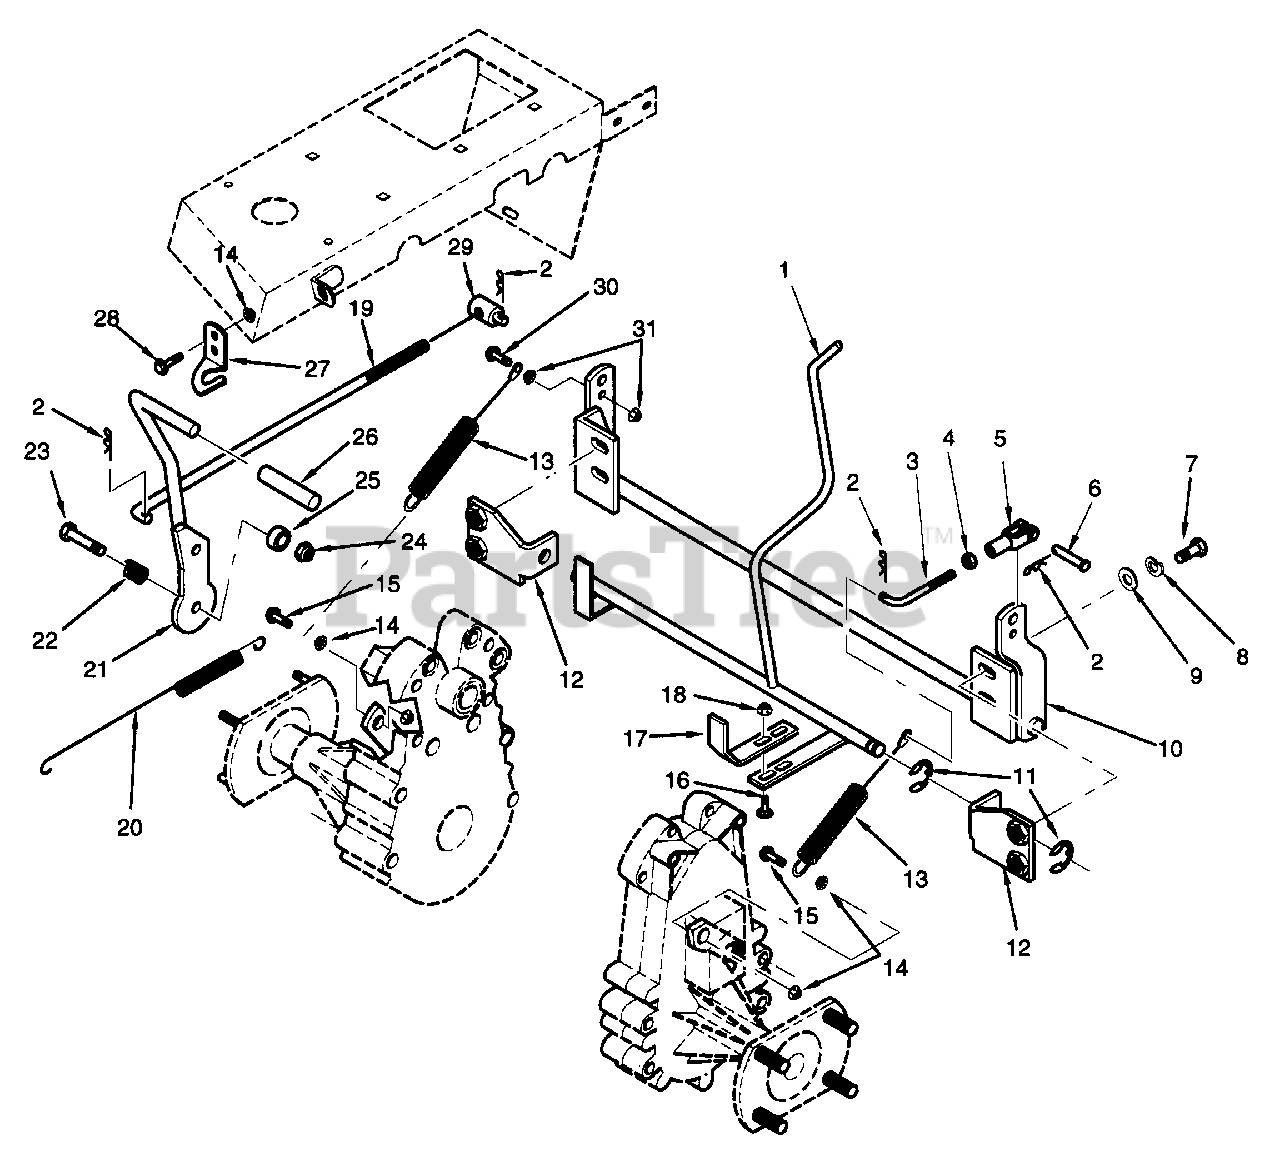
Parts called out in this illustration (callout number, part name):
1	LEVER, DUMP VALVE
2	HAIRPIN
3	ROD, BRAKE - L.H.
4	HEX NUT, 1/4-28
5	CLEVIS
6	PIN, CLEVIS, 1/4 X 3/4
7	BOLT, HEX HEAD, 3/8-16 X 1-1/2
8	LOCKWASHER, 3/8
9	FLATWASHER, 3/8(.391 X .938 X .105)
10	ACTUATOR, BRAKE
11	RING, RETAINER
12	MOUNTING BRACKET, DUMP VALVE
13	CABLE ASSEMBLY, PARKING BRAKE
14	SERR. FL. HEX NUT, 5/16-18
15	SERR. FL. HEX HEAD CPSCR, 5/16-18 X 1.00
16	CARRIAGE BOLT, 1/4-20 X 3/4
17	BRACKET, DUMP VALVE LEVER
18	SERR. FL. HEX NUT, 1/4-20
19	ROD, BRAKE - R.H.
20	SPRING
21	LEVER, PARKING BRAKE
22	SPRING, CONTROL DETENT
23	BOLT, HEX HEAD, 3/8-16 X 2-1/4
24	HEX LOCKNUT, ELASTIC STOP, 3/8-16
25	SPACER
26	GRIP, PARKING BRAKE LEVER
27	LATCH, BRAKE LEVER
28	SERR. FL. HEX HEAD CPSCRW, 5/16-18 X 3/4
29	SWIVEL JOINT
30	BOLT, HEX HEAD, 1/4-20 X 1-1/4
31	SERR. FL. HEX NUT, 1/4-20
